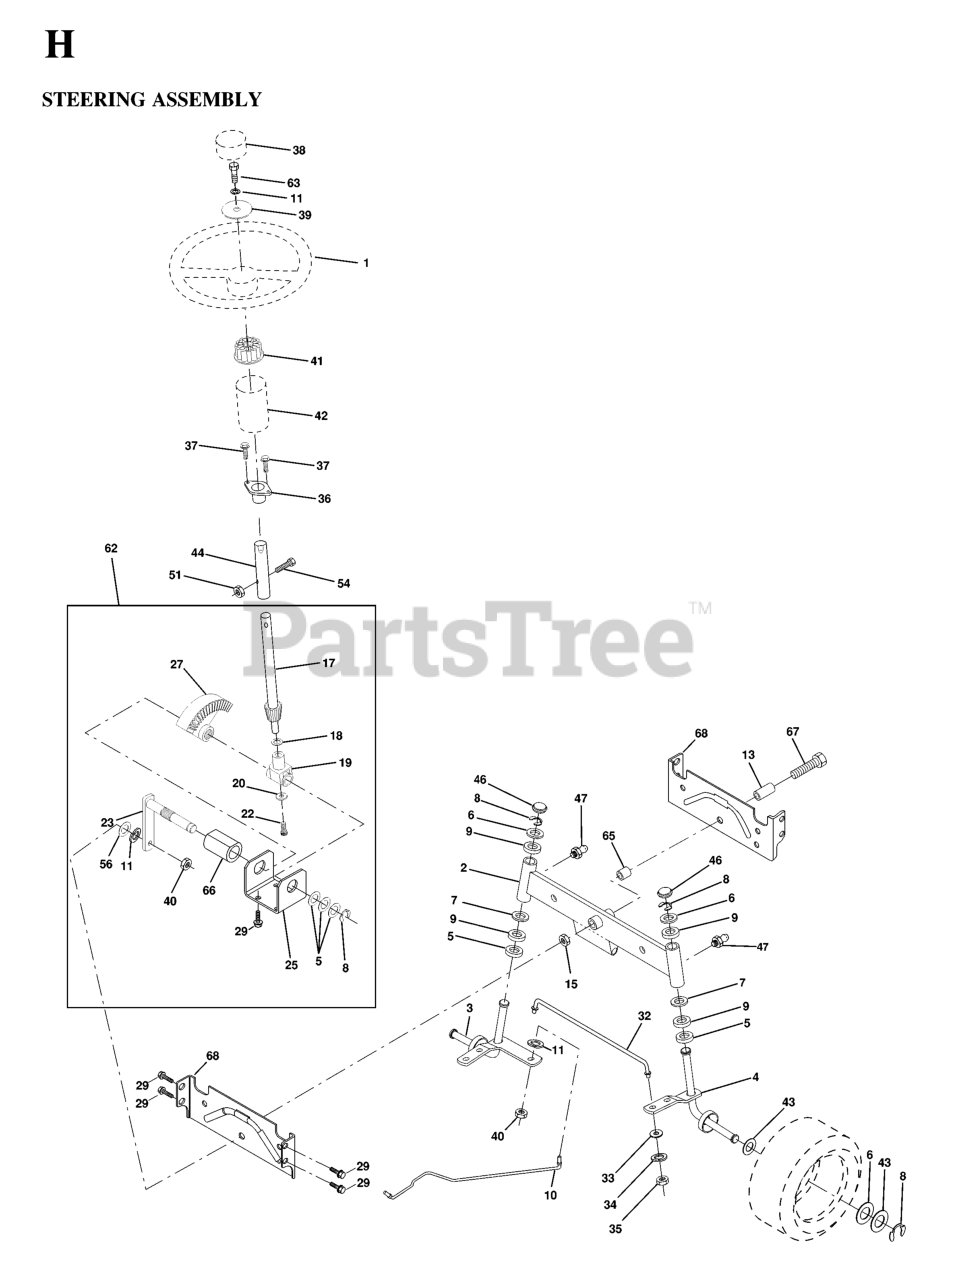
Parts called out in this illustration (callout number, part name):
1	STEERING WHEEL
2	AXLE ASSY
3	SPINDLE.ASM.LH
4	SPINDLE ASM, RH
5	THRUST WASHER
9	BRNG T
10	DRAGLINK-STAMPED
11	WASHER, LOCK 3/8
13	BEARING AXLE
15	NUT-LOC,FLANGE LT
17	SHAFT ASM STEERING
18	THRUST WASHER
19	SHAFT,SUPPORT
20	WASHER
21	LOCKWASHER
22	SCREW
23	SHAFT PITMAN
25	BRACKET STEERING
27	GEAR.SECTOR
29	SCREW
32	TIE ROD
33	WASHER M
34	LOCKWASHER
35	LOCKNUT
36	BUSHING, STEERING
37	SCREW.TT.#10-32X.5.3/8.FLANGE
38	INSERT,STR WHEEL
39	WASHER T
40	GRIPCO NUT
41	ADAPTER LT
42	BOOT, STEERING
44	EXT SHAFT STEERING
46	CAP.SPINDLE.BLACK
47	ZERK M
51	NUT.71038.31-18.HEX.NYLOCK
54	BOLT.5/16-18X1-1/4 FULL.THREAD
62	KIT, STEERING ASSEMBLY
65	REPL BY 532 15 47-80
66	BEARING ARM
67	Bolt, Hex 5/8 -11 x 2 - 3/4 Gr. 5
68	AXLE, BRACE
